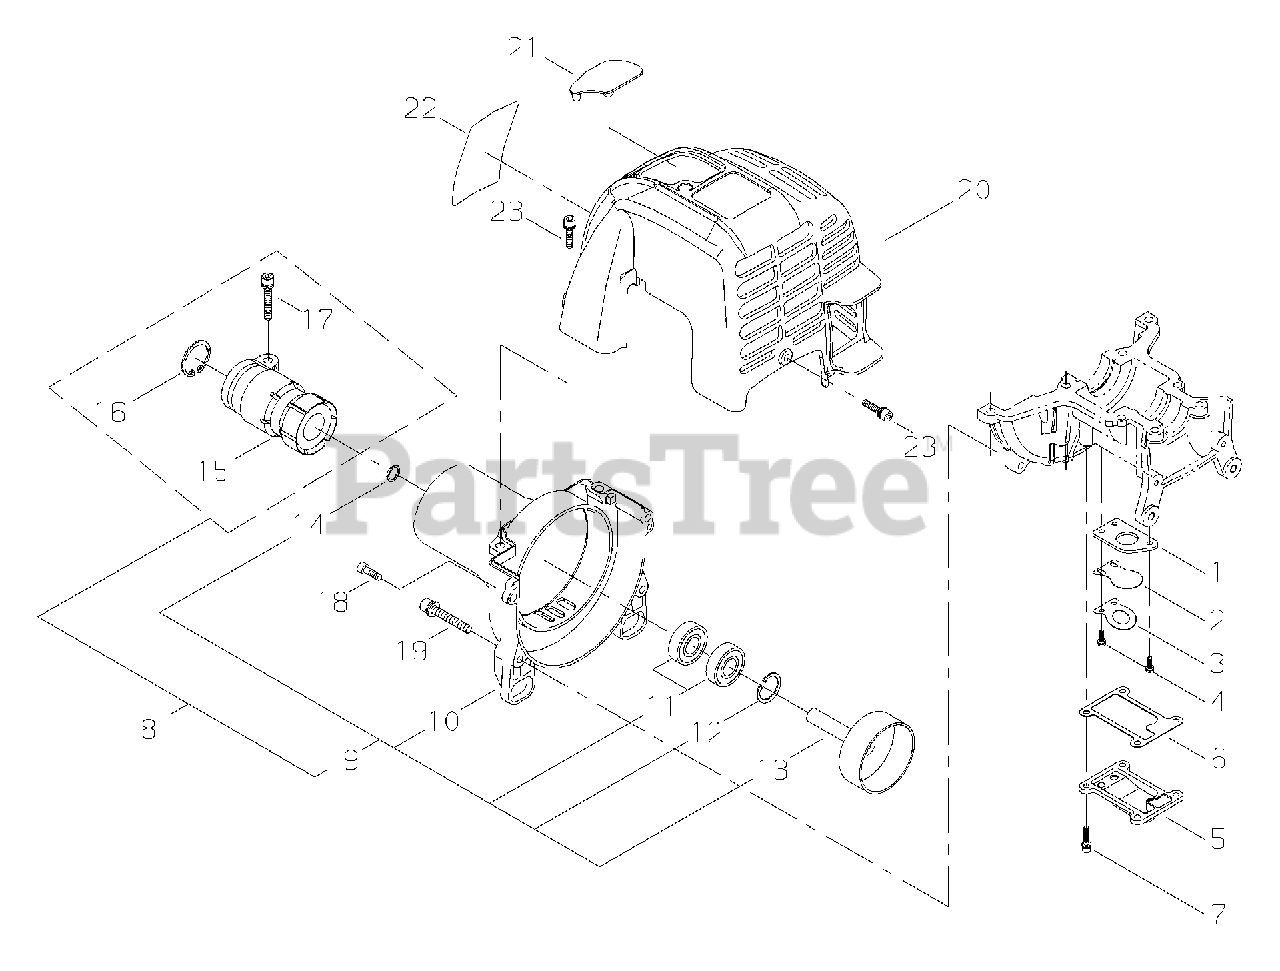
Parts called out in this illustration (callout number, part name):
1	PLATE, REED BACKING
2	VALVE, REED
3	STOP, REED VALVE
4	SCREW M3×10
5	COVER, REED VALVE
6	GASKET, REED VALVE
7	BOLT M4×14
8	COVER ASSY, FAN
9	FAN CASE ASSY
10	COVER, FAN
11	BEARING, BALL 6001 DDU C3
12	RING, SNAP Ø28
13	DRUM, CLUTCH
14	RING, SNAP Ø12
15	CUSHION, AV
16	RING, SNAP Ø42
17	BOLT M5×22
18	BOLT 5×16
19	BOLT M5×40
20	COVER, ENGINE
21	COVER, SPARK PLUG
22	LABEL - MODEL
23	BOLT M4×14
